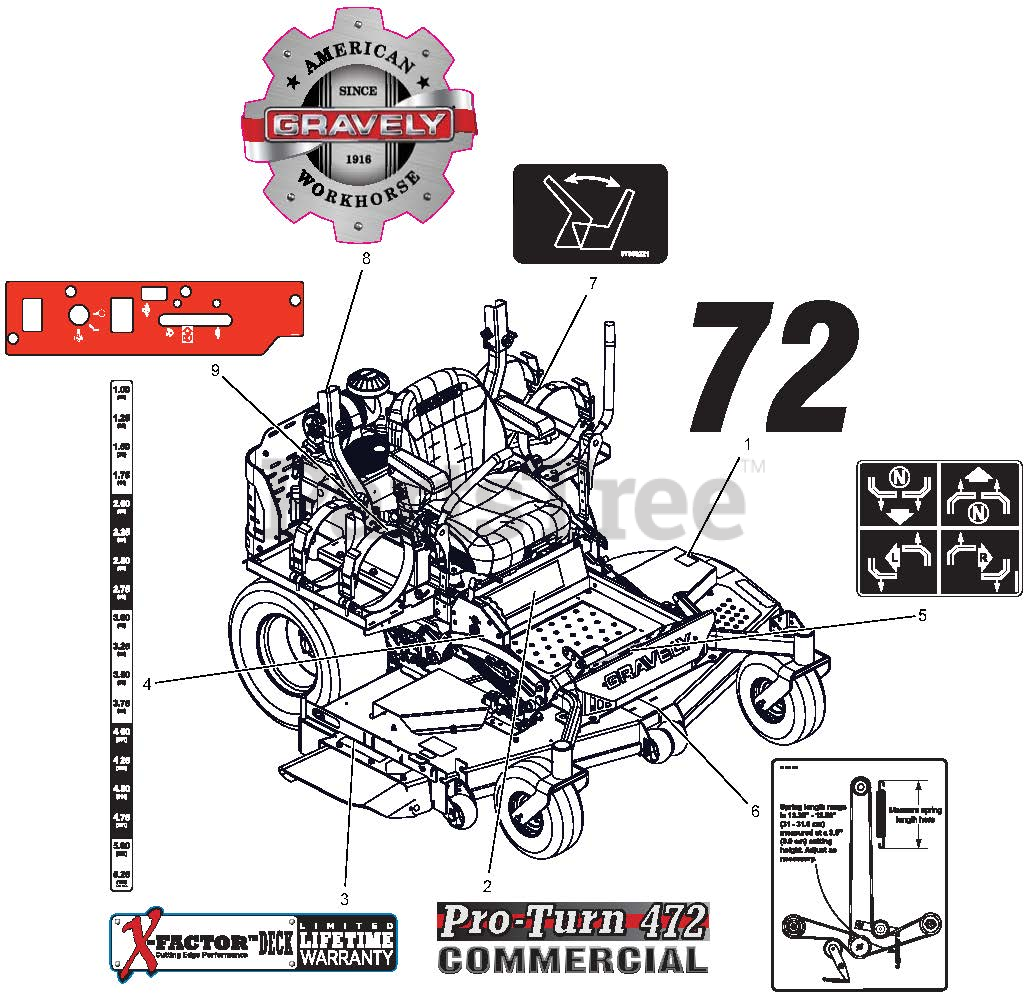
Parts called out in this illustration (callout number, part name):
1	DECAL, 72"
2	DECAL, PRO-TURN 472 COMMERCIAL
3	DECAL, X-FACTOR DECK
4	DECAL, PT400 HEIGHT OF CUT
5	DECAL, INSTRUCTIONAL - STEERING
6	DECAL, BELT DIAGRAM 60"
7	DECAL, SEAT RELEAS E
8	DECAL, GRAVELY HERITAGE-LARGE
9	DECAL, CONTROL PT400 - LP
